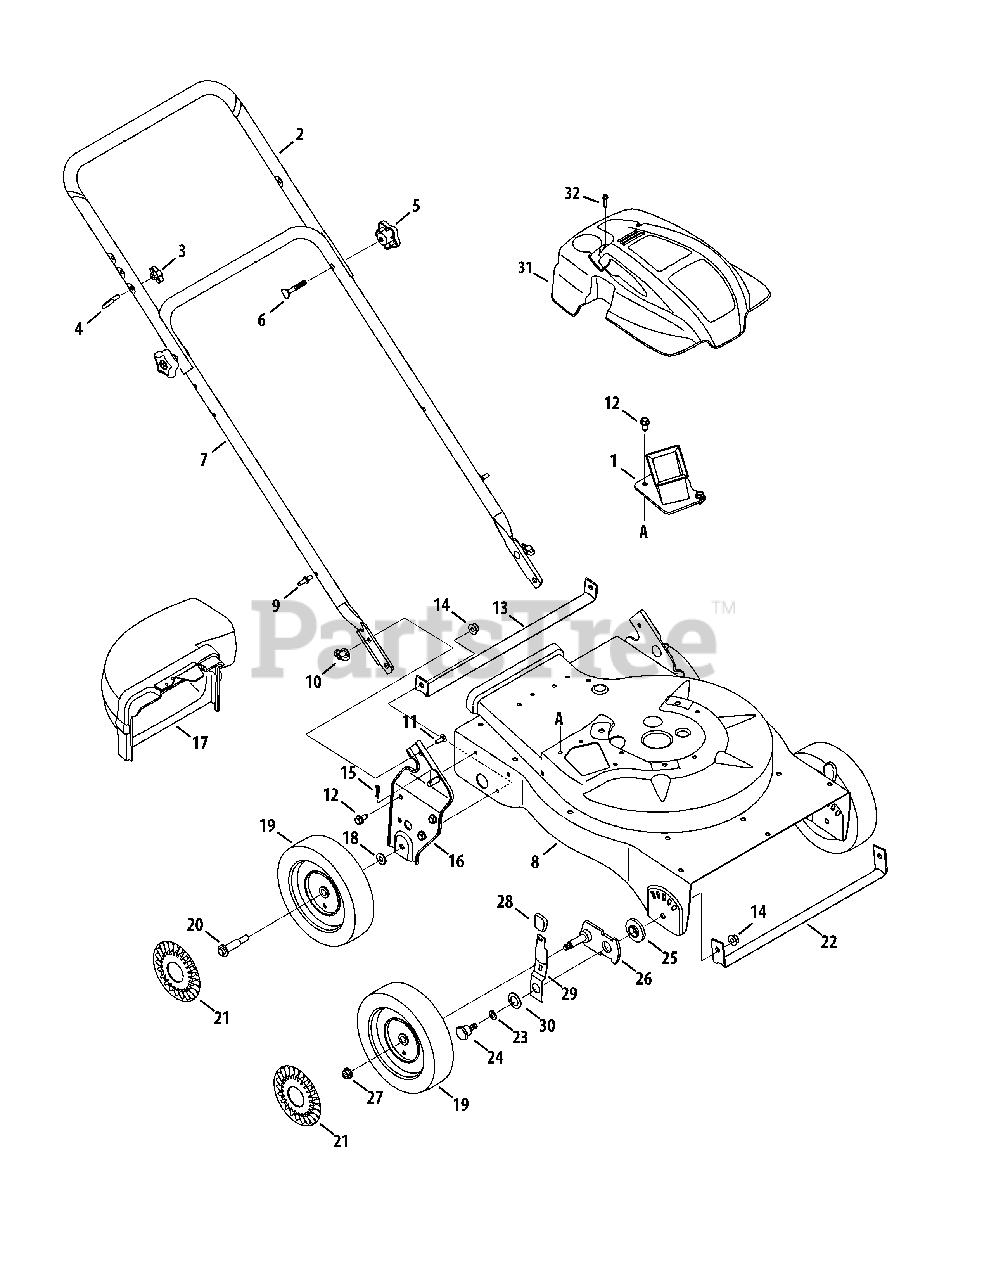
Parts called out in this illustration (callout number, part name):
1	Chipper Chute Assembly
2	Upper Handle
4	Eye Bolt
5	Star Knob, 5/16-18
6	Carriage Bolt
7	Lower Handle
8	Upper Housing
9	Studs
10	Wing Nut 1/4-20
11	Carriage Screw 1/4-20 x.75
12	Screw, 5/16-12 x.750
13	Rear Wheel Support Brace
14	Flange Lock Nut, 3/8-16
15	Cotter Pin
16	Handle Bracket Assy. LH
17	Blower Chute Assembly
18	Bell Washer.401 ID x.870 OD
19	Wheel, 8 x 1.8, Bar
19	Wheel, 8 x 2.125, Zag
20	Shoulder Screw 3/8-16
21	Hub Cap
22	Front Wheel Support Brace
23	Thrust Washer.375 ID x.70 OD
24	Shoulder Screw, .750 ID x .500
25	Height Adjustment Bearing
26	Pivot Arm Assembly
27	Flange Lock Nut, 3/8-16
28	Height Adjustment Knob
29	Spring Lever
30	Bell Washer.760 ID x.25OD
31	Engine Shroud
32	Screw, #12-16 x 1.00
